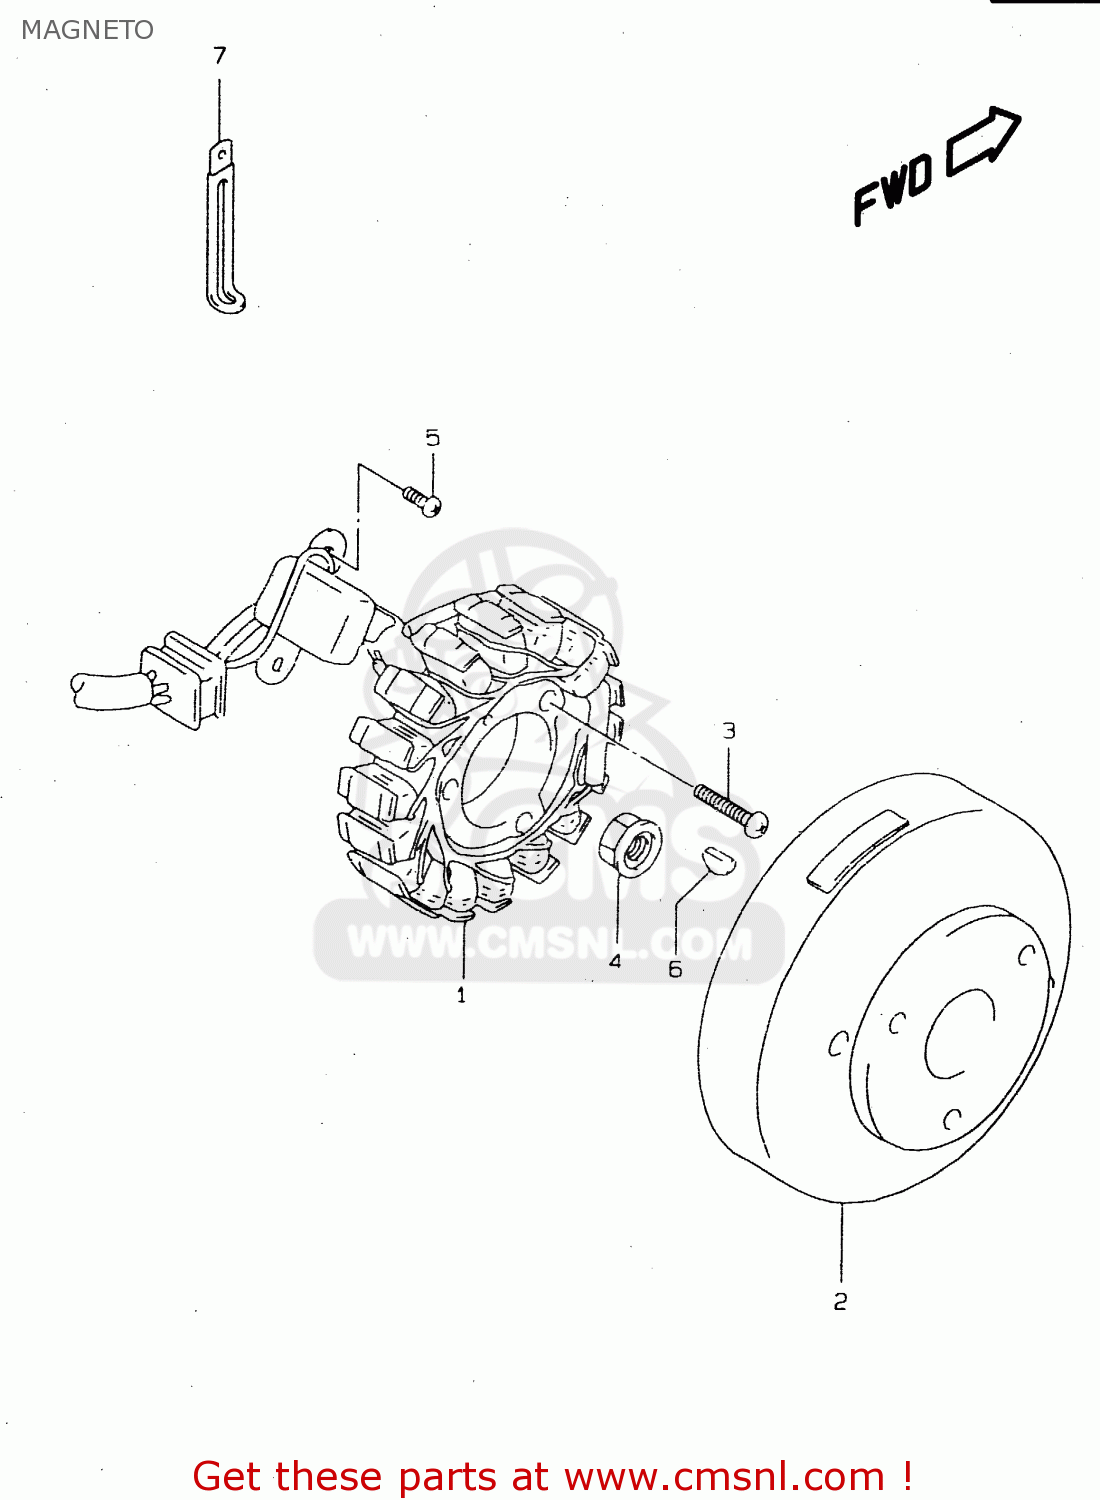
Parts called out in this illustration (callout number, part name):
1	STATOR ASSEMBLY
2	ROTOR ASSY
3	SCREW
4	NUT
5	SCREW
6	KEY
7	CLAMP(L:80)
